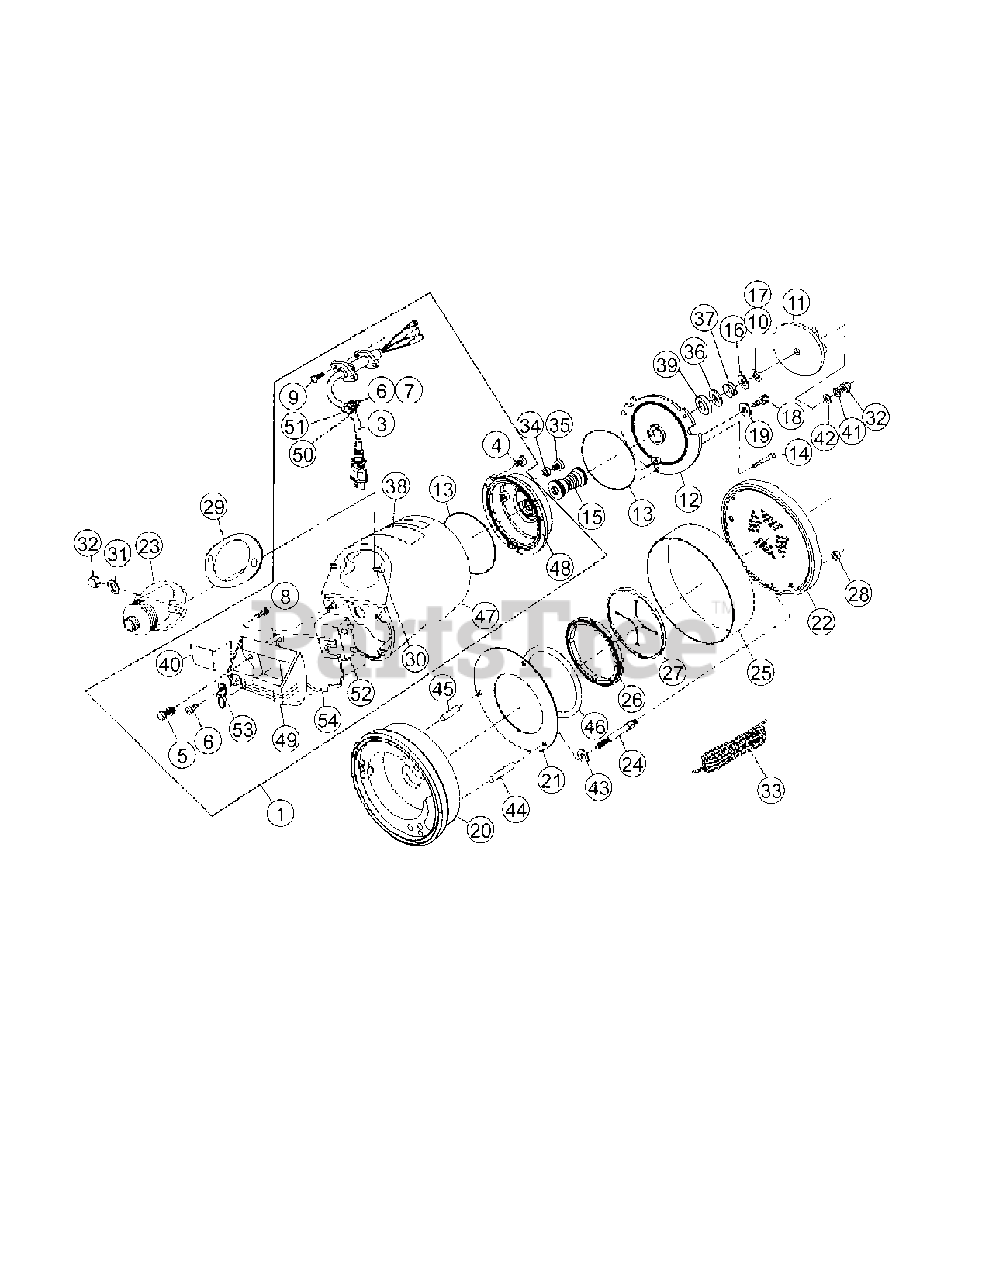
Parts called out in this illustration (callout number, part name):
3	Power Cord
4	Hex Bolt
5	Hex Bolt
6	Screw
7	Nut
8	Screw
9	Screw
10	Adjusting Washer
11	Impeller
12	Front Cover
13	O ring
14	Hex Socket Bolt
15	Mechanical Seal
16	Adjusting Washer
18	Hex Socket Bolt
19	Seal Washer
20	Casing
21	Suction Cover
22	Bottom Strainer
23	Delivery Flange
24	Stud Bolt
25	Strainer Stand
26	Seal Ring
27	Check Valve
28	Nut
29	Delivery Gasket
30	Stud Bolt
31	Washer
32	Cap Nut
33	Rope
34	Seal Ring
35	Screw
36	Thrust Washer
37	Oil Seal
38	Label
39	Thrust Washer Gasket
40	Label
41	Toothed Washer
42	Washer
43	Seal Washer
44	Spacer, long
45	Spacer, short
46	Suction Cover Gasket
47	Motor Frame
48	Bracket
49	Handle
50	Cord Supporter
51	Cord Band
53	Chain Ay
54	Head Gasket
